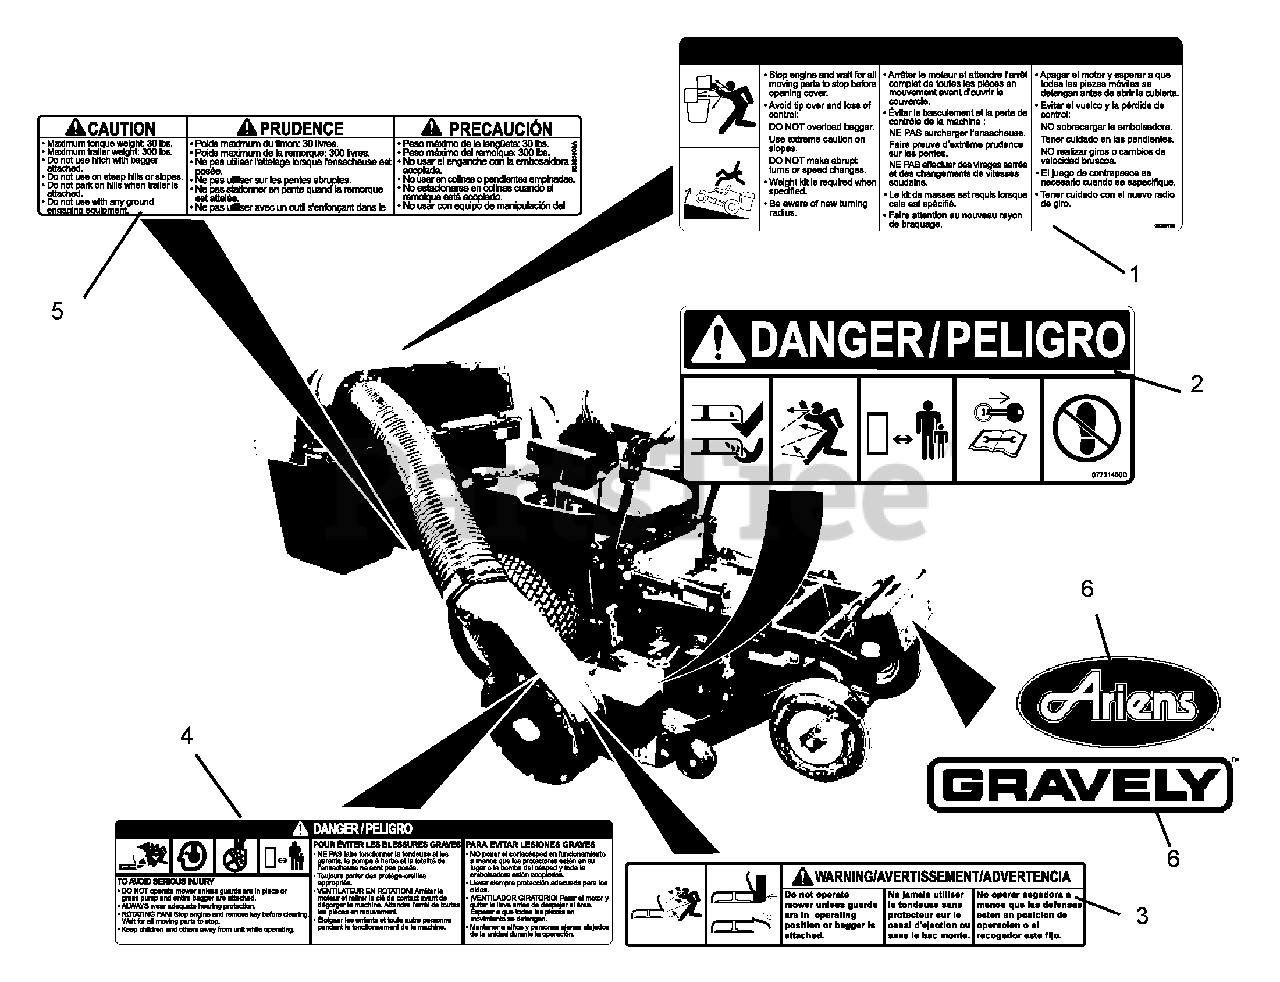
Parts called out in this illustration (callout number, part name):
1	DECAL, BAGGER COVER
2	DECAL, MOWER PAN DANGER
3	DECAL, WARNING
4	DECAL-CAUTION, GRASS PUMP
5	DECAL, TRAILER HITCH
6	DECAL - 15" GRAVELY LOGO
